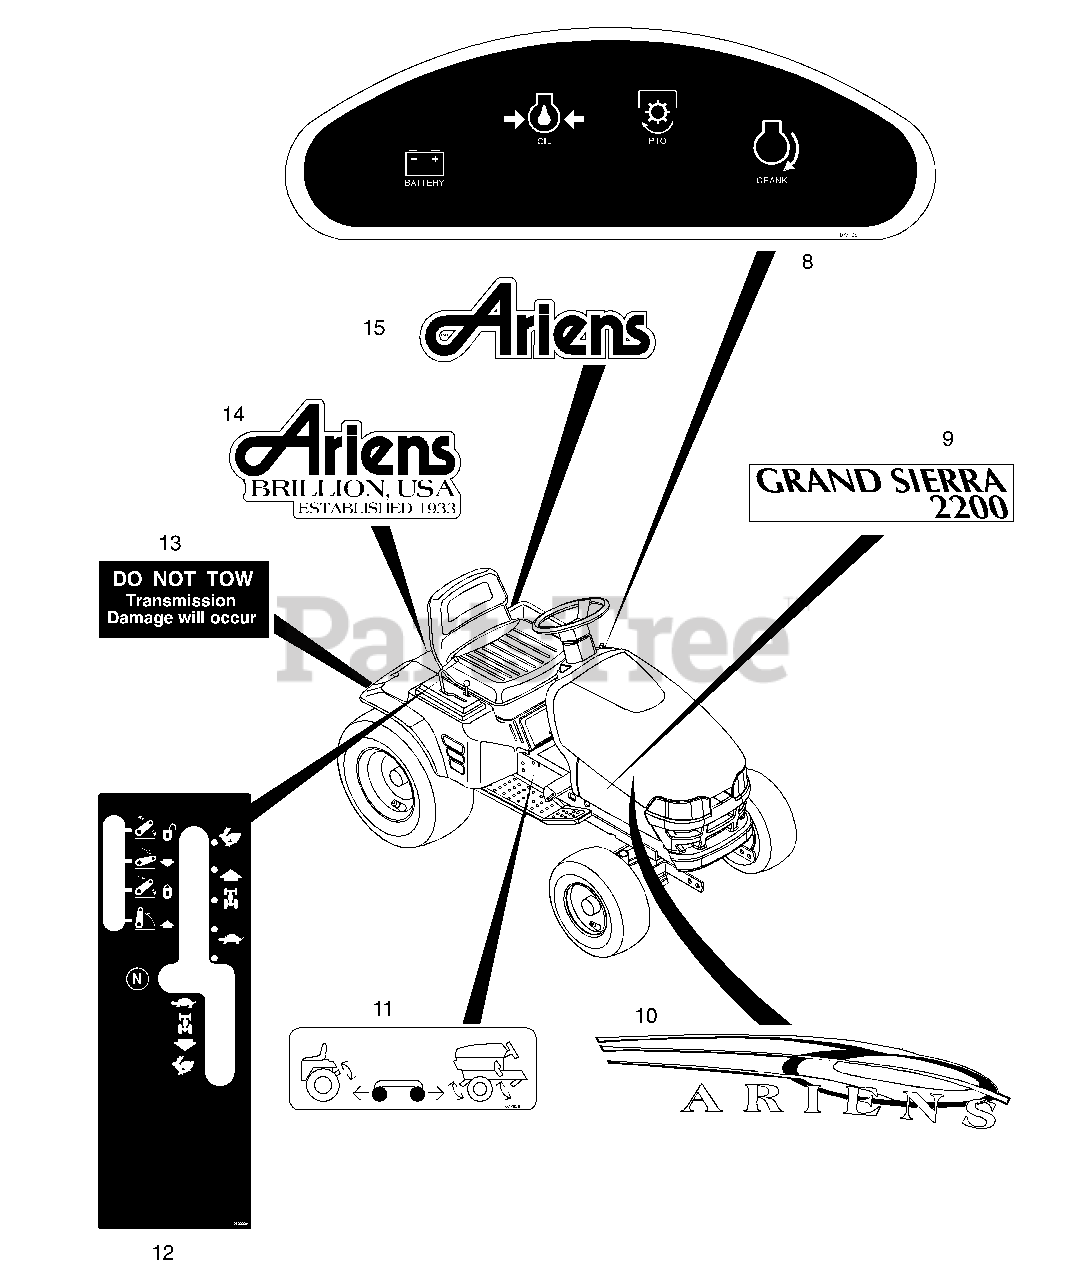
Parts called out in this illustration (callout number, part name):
8	DECAL - DASH W/LIGHTS
9	DECAL - GRAND SIERRA 2200 - L
9	DECAL - GRAND SIERRA 2200 - R
10	DECAL- ARIENS HOOD LOGO- R
10	DECAL- ARIENS HOOD LOGO- L
11	DECAL - LIFT SELECTOR
12	DECAL, CONTROL CONSOLE
13	TRANSMISSION DECAL
14	DECAL- ARIENS EST. 1933
15	DECAL-ARIENS
